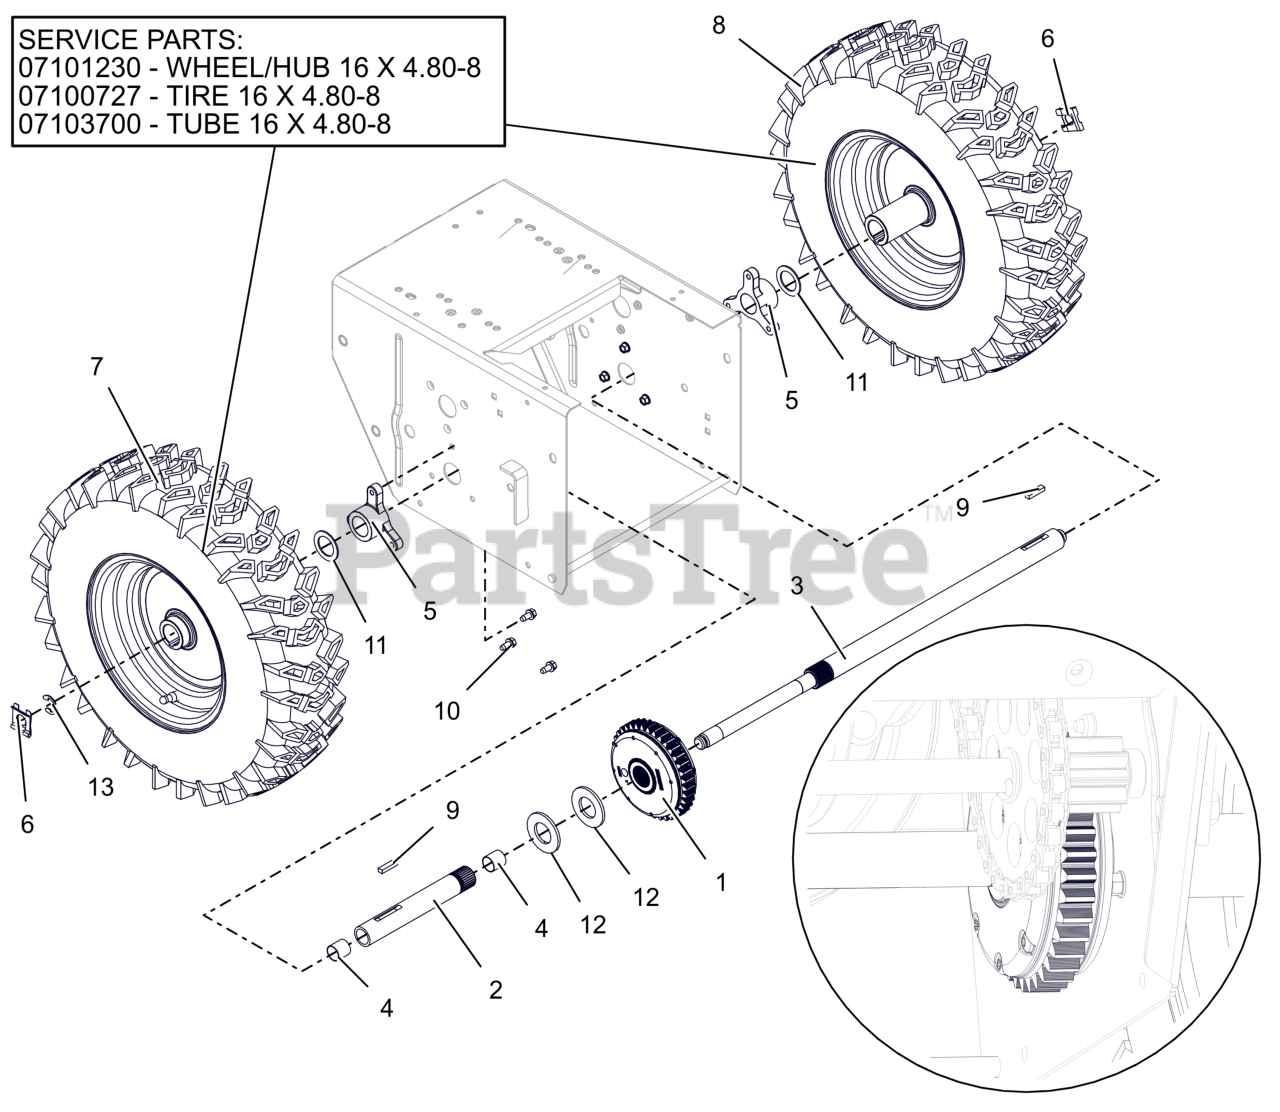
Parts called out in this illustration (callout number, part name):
1	DIFFERENTIAL, AUTOMATIC
2	AXLE, SHORT - W/BUSHINGS
3	AXLE,LONG-DELUXE AUTO DIFF
4	BSHG-SLV .706X.764X.75 BRZ
5	BUSHING, AXLE
6	CLIP, SNAP .625 DIA
7	TIRE/WHEEL,RH 16X4.8-8 DIFF T2
8	TIRE/WHEEL,LH 16X4.8-8 DIFF T2
9	KEY-RECT .25X.188X1.00
10	SCR-TAP .25-20X.50 HWH ZCC
11	WSHR, FLT 1.010X1.505X.062 ZCC
12	WSHR, FLT 1.062X2.000X.134 ZCC
13	RG-RTNG-EXT .625X.042
